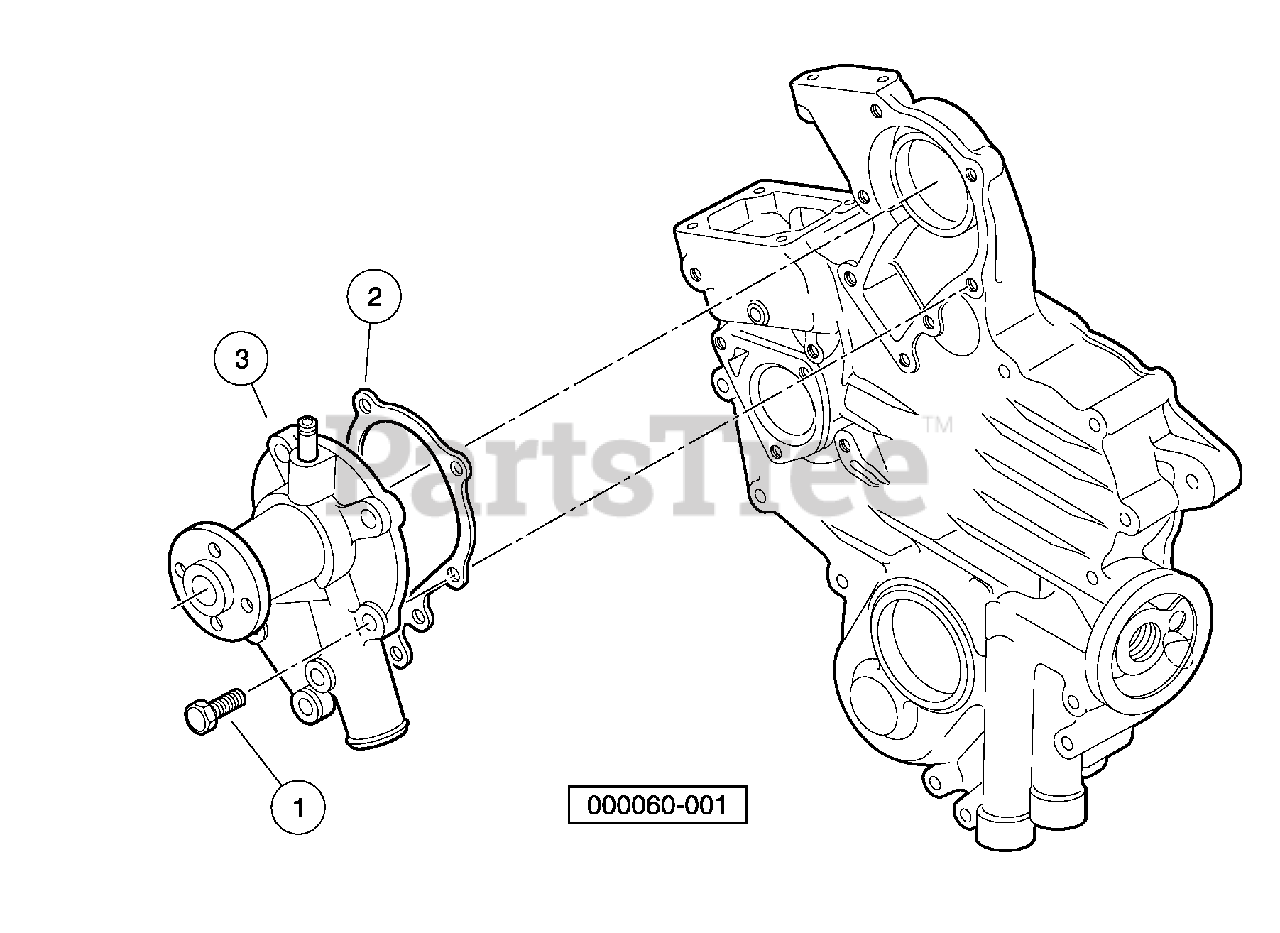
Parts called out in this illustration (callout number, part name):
1	Bolt, M6 X 1 X 22
2	Gasket, Water Pump, D722
3	Water Pump Assembly
